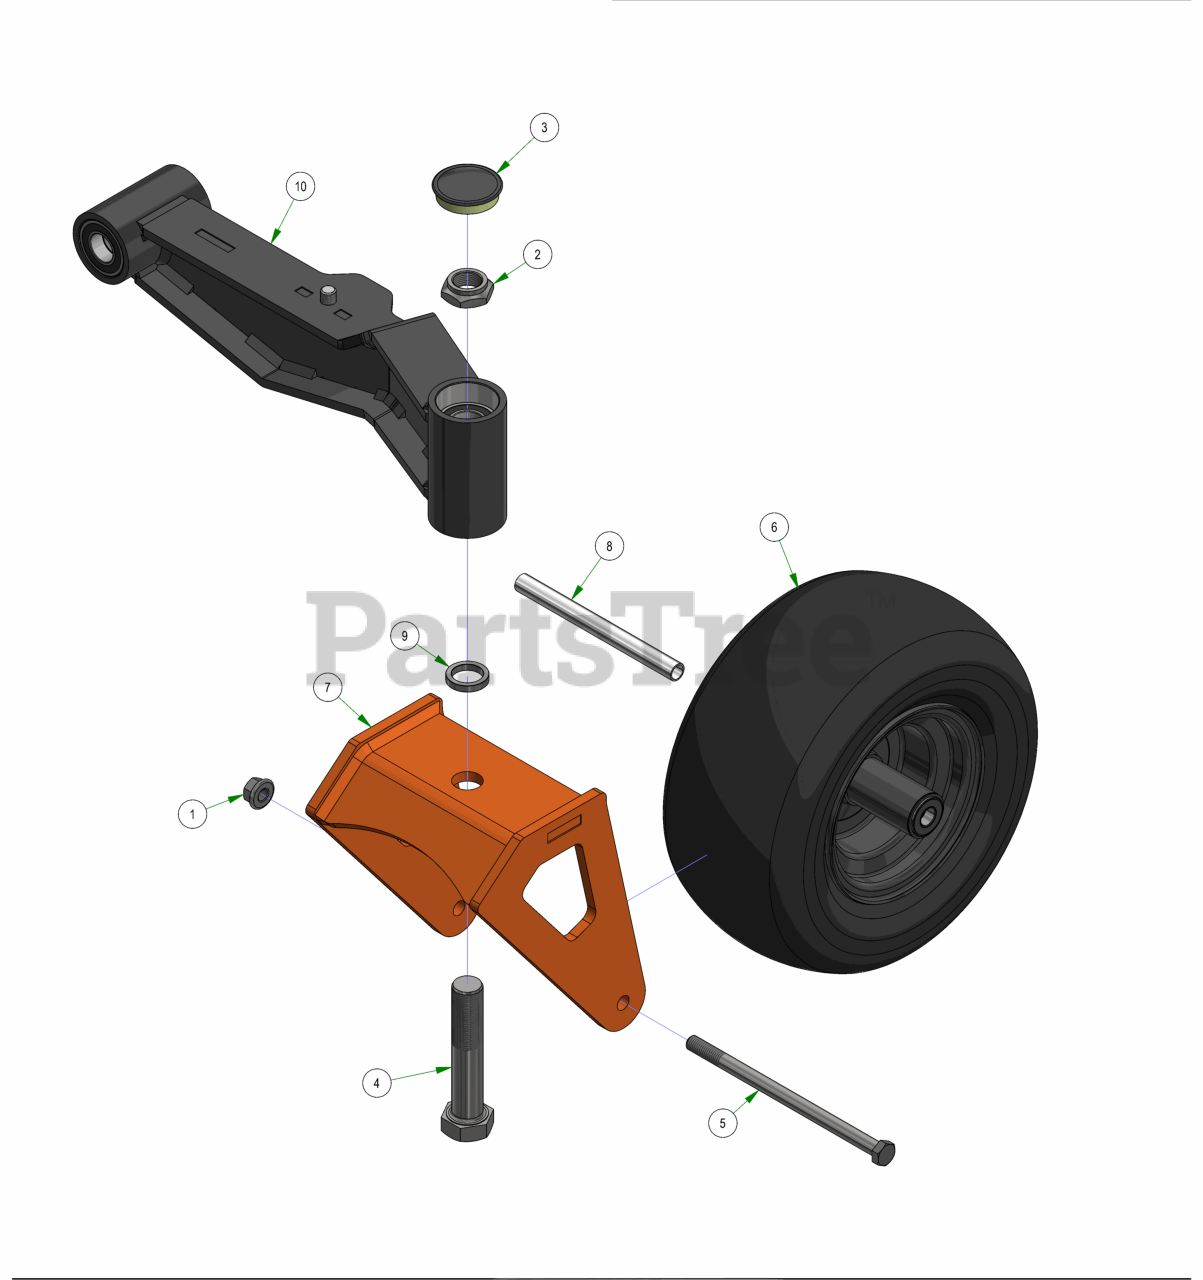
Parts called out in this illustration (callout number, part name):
1	1/2-13 NYLON INSERT FLANGE LOCKNUT ZINC
2	1"-14 NYLON INSERT JAM LOCKNUT ZINC
3	2017 Bearing Cover
4	1"-14 X 5 HEX CAP SCREW (GR.8) ZINC YELLOW
5	1/2-13 X 8-1/2 HEX CAP SCREW (GR.5) ZINC
6	13x6.5-6 Black Tire and Wheel Assembly
7	2019 Stand-on Front Fork Weldment
8	Front Wheel Spanner
9	1.02 ID X 1.38 OD X .250 THK SPACER ZINC
10	2021 Maverick LH Front Suspension Arm Assy (48", 54" & 60")
